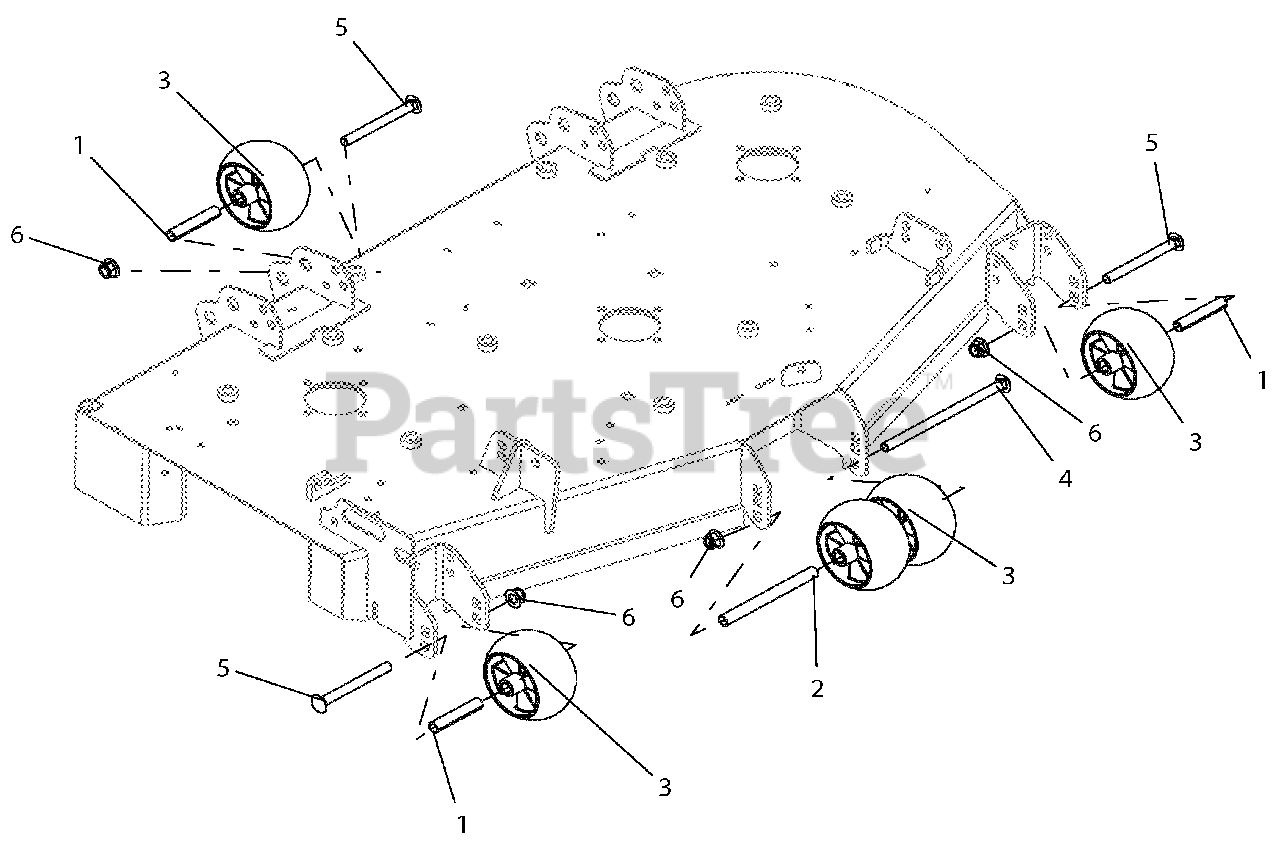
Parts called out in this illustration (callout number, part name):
1	SPACER, .510X.625X3.35
2	SPACER, .510 X .625 X 6.50
3	ANTI-SCALP WHEEL - 5X3 CTR
4	BLT-RDHDSQNK .50-13X8.50 Y
5	BLT-RDHDSQNK .50-13X5.00 G5 YWZC
6	NUT-LK-NYL-FLG .50-13 YWZC
